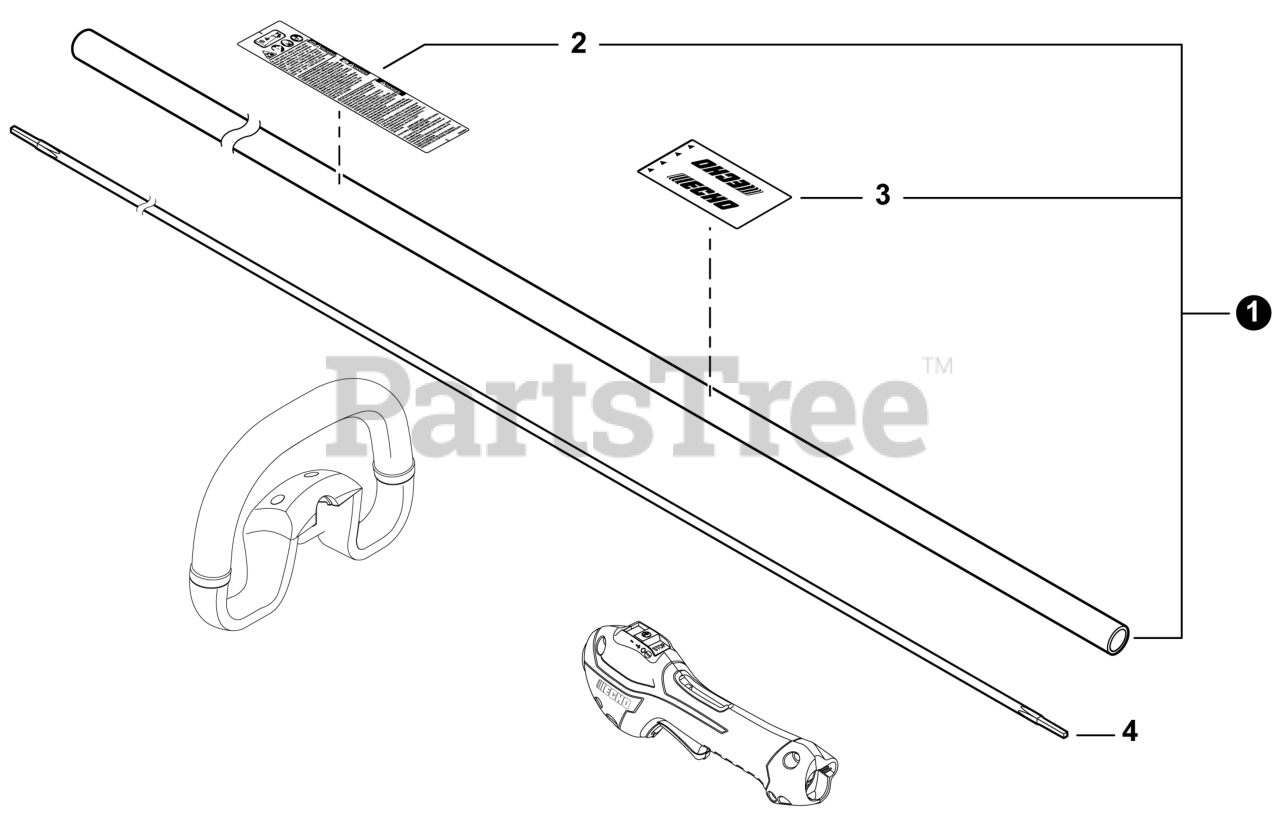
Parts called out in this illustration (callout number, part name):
1	MAIN PIPE ASSY
2	LABEL - CAUTION
3	LABEL - HANDLE LOCATION
4	DRIVESHAFT - FLEXIBLE
